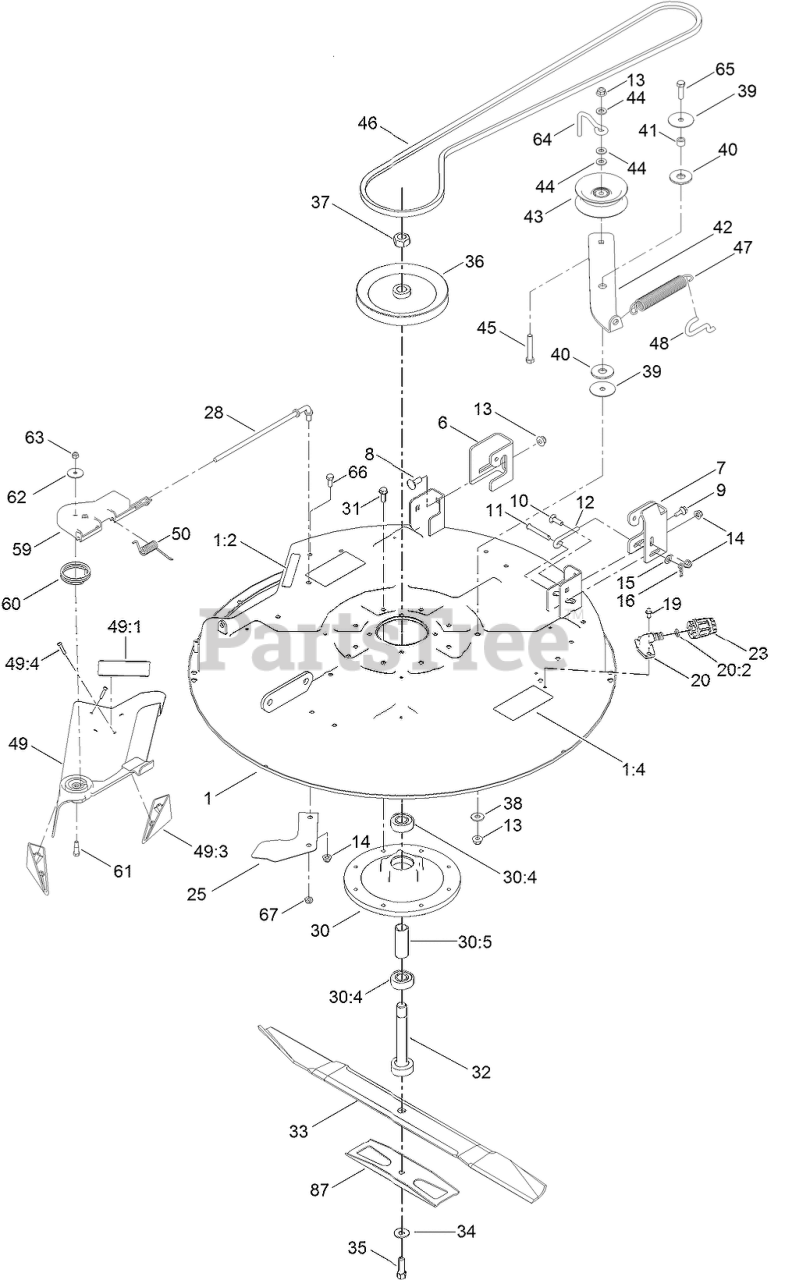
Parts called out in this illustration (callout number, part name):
1	32 INCH DECK AND DECAL ASM
1:2	DECAL-DANGER
1:4	DECAL-DANGER, DECK
6	BRACKET-HANGER, RH
7	BRACKET-HANGER, LH
8	BOLT-CARR
9	SCREW-SHOULDER,HWH
10	SCREW-CARR
11	PIN-CLEVIS
12	ROD-LEVEL, DECK
13	NUT-HF, NI
14	NUT-HF, NI
15	WASHER-PLAIN
16	PIN-COTTER
19	SCREW-HWH
20	FITTING-WASHOUT
20:2	O-RING
23	CONNECTOR-HOSE
25	RAMP-DEFLECTOR
28	ROD-PIVOT
30	SPINDLE HOUSING ASM
30:4	BEARING-BALL
30:5	SPACER-BEARING
31	SCREW-TAPTITE
32	SHAFT-SPINDLE
33	BLADE-RECYCLER, 31.35 INCH
34	WASHER-BELLEVILLE
35	SCREW-HH
36	PULLEY - 32" DECK
37	NUT-HEX
38	WASHER-HARDENED
39	WASHER
40	WASHER-FRICTION, COMPOSITE
41	SPACER
42	ARM-IDLER
43	PULLEY-IDLER, FLAT
44	WASHER-FLAT
45	SCREW-HH
46	V-BELT
47	SPRING-EXTENSION
48	HOOK-RETURN, SPRING
49	32 INCH DEFLECTOR ASM
49:1	DECAL-DANGER
49:3	KICKER
49:4	SCREW-PPH
50	SPRING-TORSION
59	PIVOT-HINGE, DEFLECTOR
60	SPRING-TORSION
61	BOLT-SHOULDER
62	WASHER-FLAT
63	NUT-LOCK, NI
64	GUIDE-IDLER, BELT
65	SCREW-HH
66	SCREW-HH
87	STIFFENER
